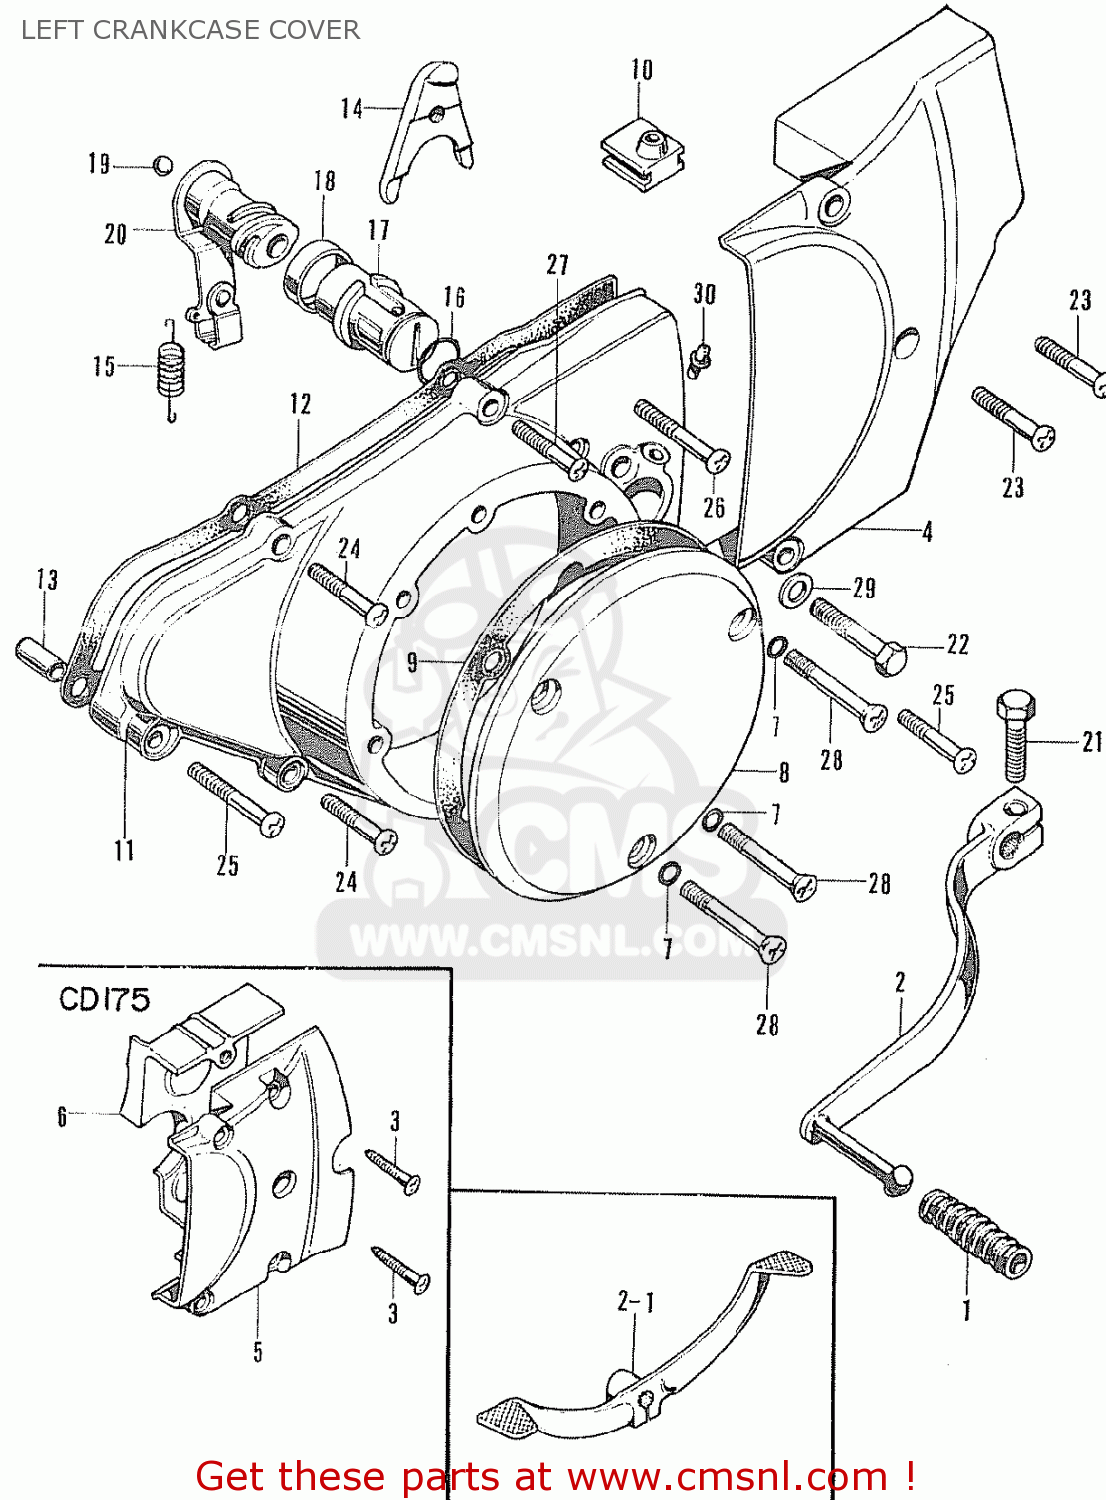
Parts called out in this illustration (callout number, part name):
1	RUBBER,PEDAL
2	PEDAL,GEAR CHANGE
4	COVER,A,CHAIN
7	O RING, 5.5X1.5
8	COVER,DYNAMO
9	GASKET, DYNAMO (MCA)
10	JOINT CLUTCH
11	COVER,L CRANKCASE
12	GASKET,L COVER (MCA)
13	PIN,KNOCK 10X14
14	ADJUSTER FIXING
15	SPRING LEVER
16	O RING,23MM
17	ADJUSTER,CLUTCH
18	OIL-SEAL
19	BALL, STEEL, 5/16
20	THREAD CLUTCH
21	BOLT,HEX 6X20
22	BOLT,HEX 6X36
23	SCREW,CROSS 6X20
24	BOLT,HEX 6X25
25	SCREW,CROSS 6X32
26	SCREW,CROSS 6X36
27	SCREW,CROSS 6X40
28	SCREW,OVAL 6X40
29	WASHER,PLAIN, 6MM
30	NIPPLE,GREASE4.5
